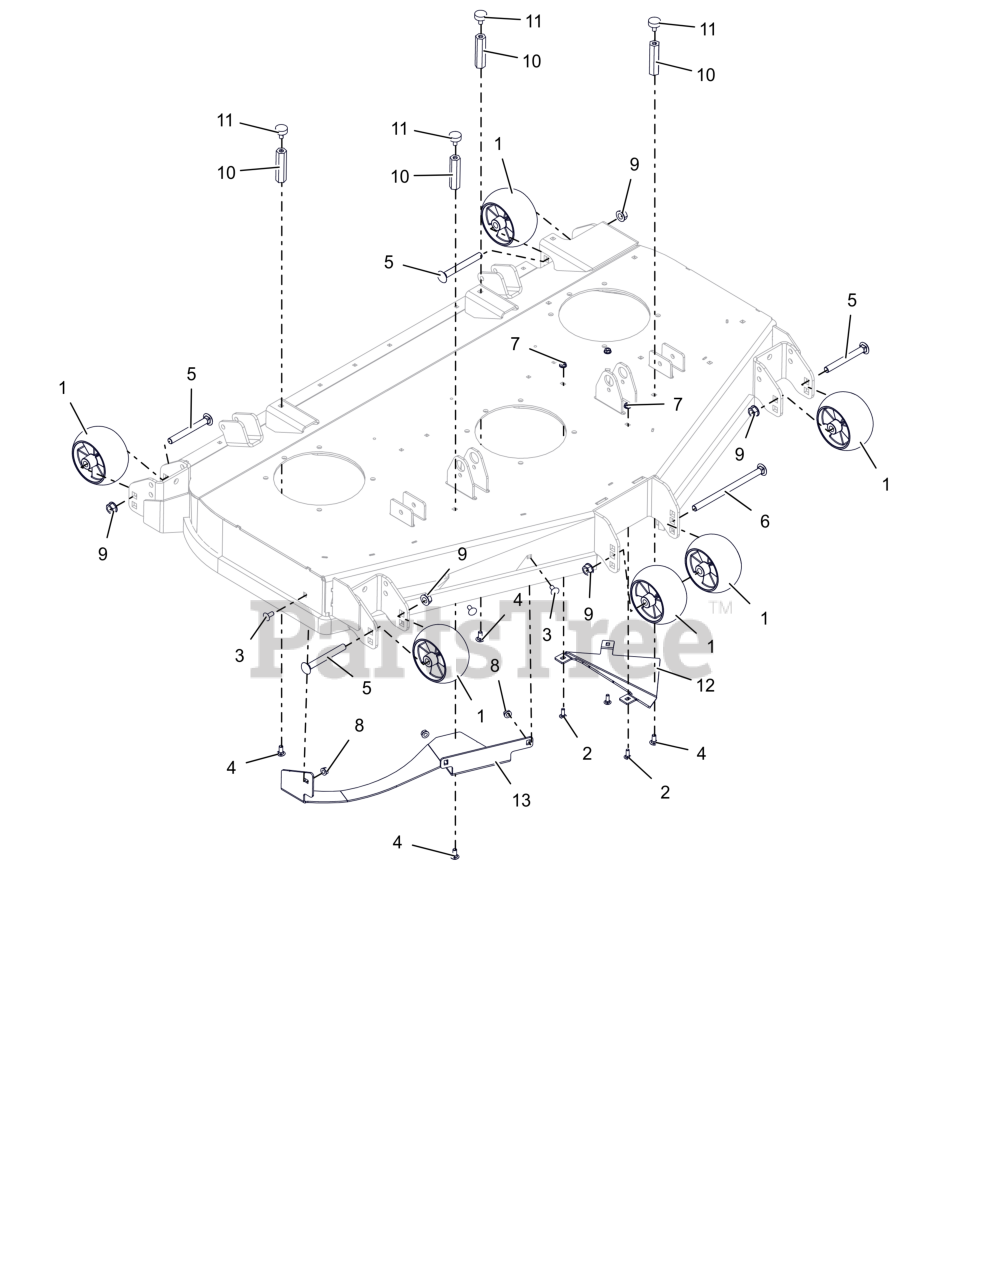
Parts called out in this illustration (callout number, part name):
1	WHEEL, ANTI SCALP - 5X3 CTR W/RIBS
2	BLT, RHSN .25-20X.750 G5 ZCC
3	BLT, RHSSN.31-18X.750 G5 ZCC
4	BLT, RHSN .31-18X.75 G5 ZCC LT
5	BOLT, RHNS .50-13X4.50 G5 ZCC NS
6	BOLT, RHNS .50-13X8.00 G5 ZCC NS
7	NUT-LK-CTR-FLG .25-20 ZC120
8	NUT,LK-CTR-FLG .31-18 GF ZCC
9	NUT-LK-CTR-FLG .500-13 GG ZCC
10	NUT, COUPLING .31-18 X 3.00
11	BUMPER, RUBBER
12	BAFFLE, 52" TRIANGLULAR INSERT (ORANGE)
13	DEFLECTOR, 52" BOLT-IN BAFFLE (ORANGE)
